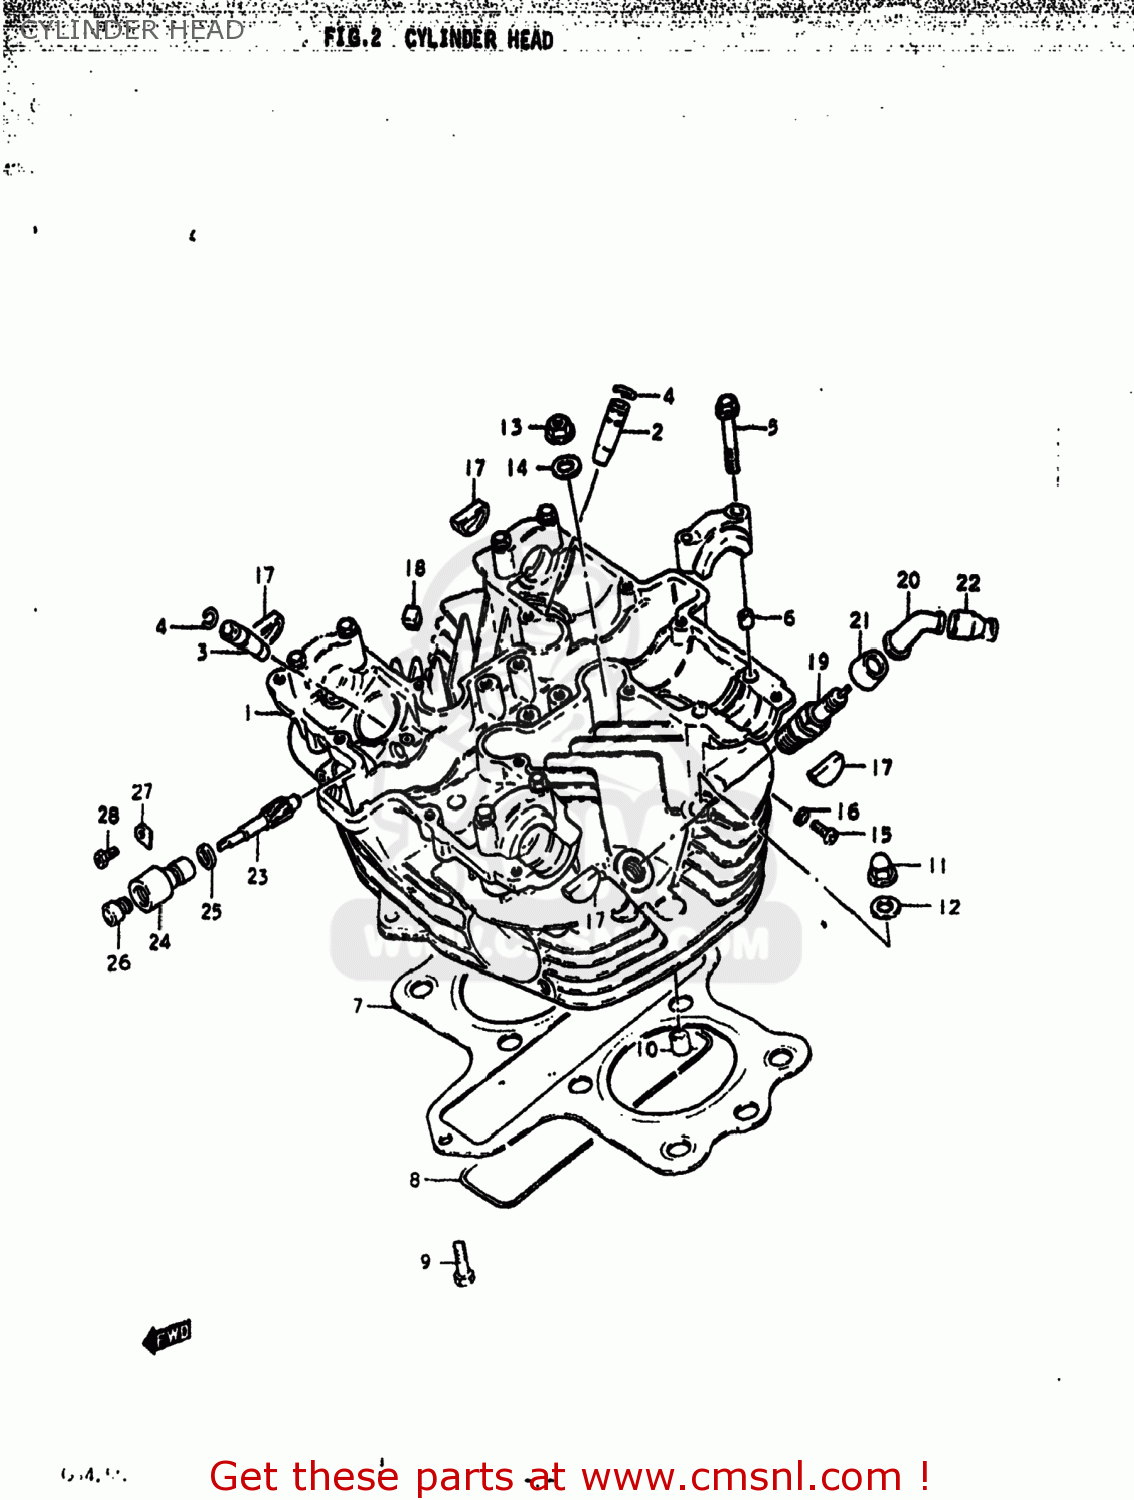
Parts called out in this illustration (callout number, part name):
1	HEAD SET,CYLINDER
2	GUIDE,VALVE
3	GUIDE,VALVE
4	RING,SNAP
5	BOLT(6X39)
6	PIN(6.2X8X11)
7	GASKET,CYLINDER HEAD (MCA)
8	O RING(D:3,ID:26X157)
9	BOLT
10	PIN
11	NUT
12	GASKET(10.5X22X2) (NAS)
13	NUT
14	WASHER(10.5X22X2.3)
15	SCREW 5X20
16	GASKET(5.3X9.3X1.2) (NAS)
17	PLUG
18	PAD
19	PLUG,SPARK
20	CAP,SPARK PLUG
21	SEAL,SPARK PLUG
22	SEAL,SPARK PLU
23	GEAR,TACHOMETER DRIVEN
24	SLEEVE,TACHOMETER DRIVE
25	SEAL,TACHOMETER DRIVEN
26	SEAL
27	PLATE,TACH DRIVE GEAR SLEEVE
28	SCREW(5X12)
